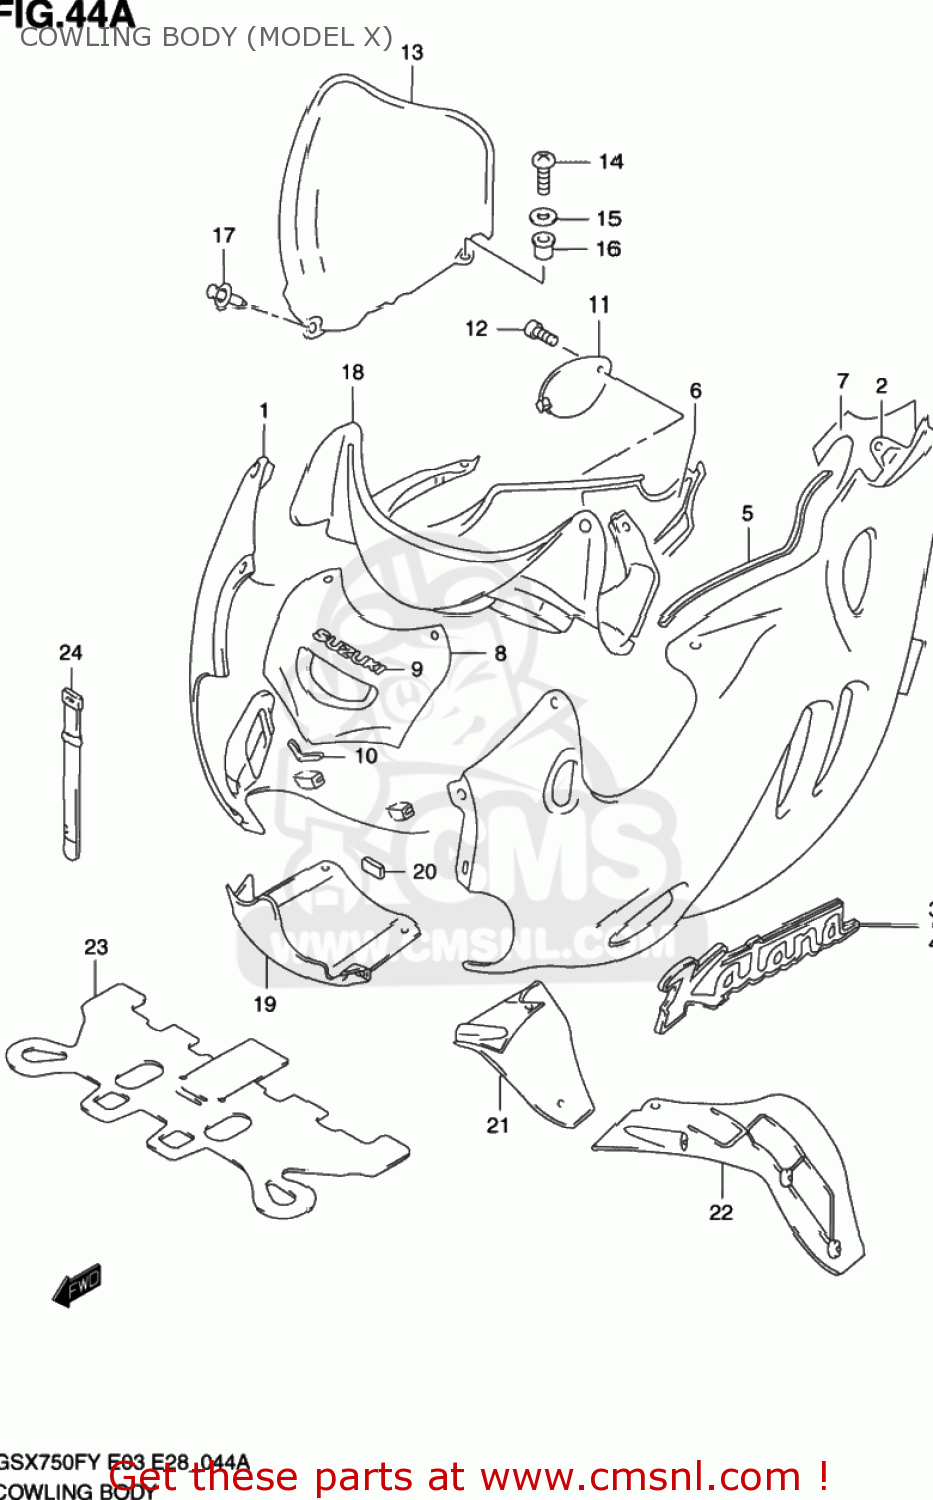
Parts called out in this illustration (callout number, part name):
1	COWLING ASSY,SIDE,R
2	COWLING ASSY,SIDE,L
3	EMBLEM,COWLING SIDE,KATANA,R
4	EMBLEM,COWLING SIDE,KATANA,L
5	MOLD,COWLING
6	SHIELD,COWLING COVER,R
7	SHIELD,COWLING COVER,L
8	PANEL,COWLING CTR UPR
9	EMBLEM,SUZUKI(SILVER)
10	CUSHION,CTR PANEL UPR
11	LID,OIL
12	SCREW(6X16)
13	WINDSCREEN
14	SCREW(5X14)
15	WASHER
16	NUT
17	CLIP(BLACK)
18	PANEL,METER
19	PANEL,COWLING CTR LWR
20	CUSHION,CENTER PANEL,LOWER
21	PANEL,COWLING,INNER,RIGHT
22	PANEL,COWLING,INNER,LEFT
23	PLATE,AIR GUIDE
24	CLAMP(L:165)
